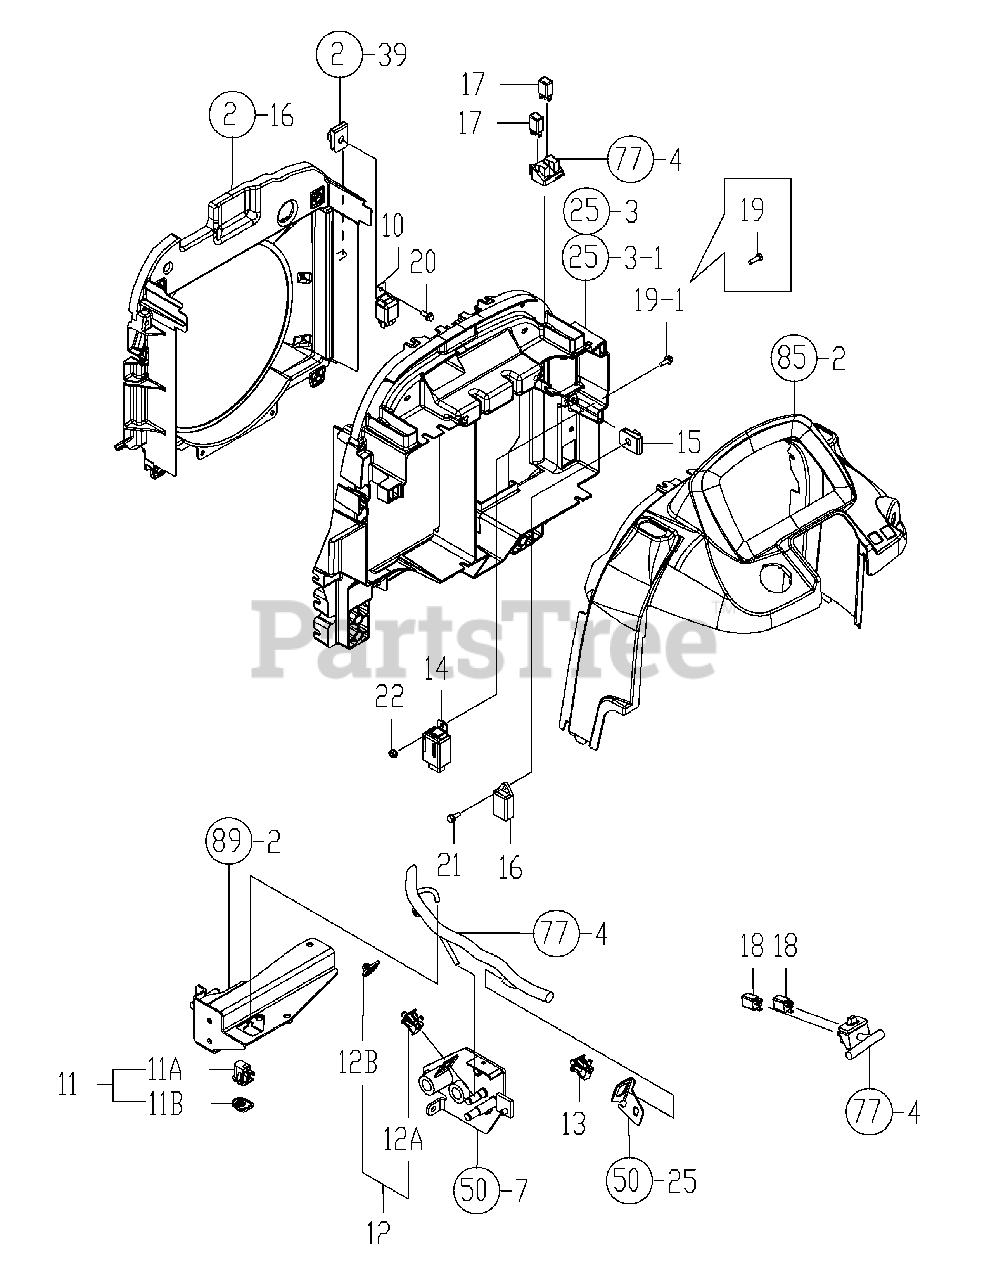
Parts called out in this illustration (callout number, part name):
10	RELAY, STARTER
11	SWITCH NC ASSEMBLY PEDAL
11A	SWITCH NC, PEDAL
11B	PROTECTIVE COVER
12	SWITCH NC ASSEMBLY PEDAL
12A	SWITCH NC, PEDAL
12B	PROTECTIVE COVER
13	SWITCH, SEAT DELTA AS
16	TIMER, FUEL SOLENOID 1 SEC
17	RELAY,STARTER ACM 13211M01
18	RELAY,STARTER ACM 13211M01
19	BOLT, 6 X 20
19-1	BOLT, 6 X 16
